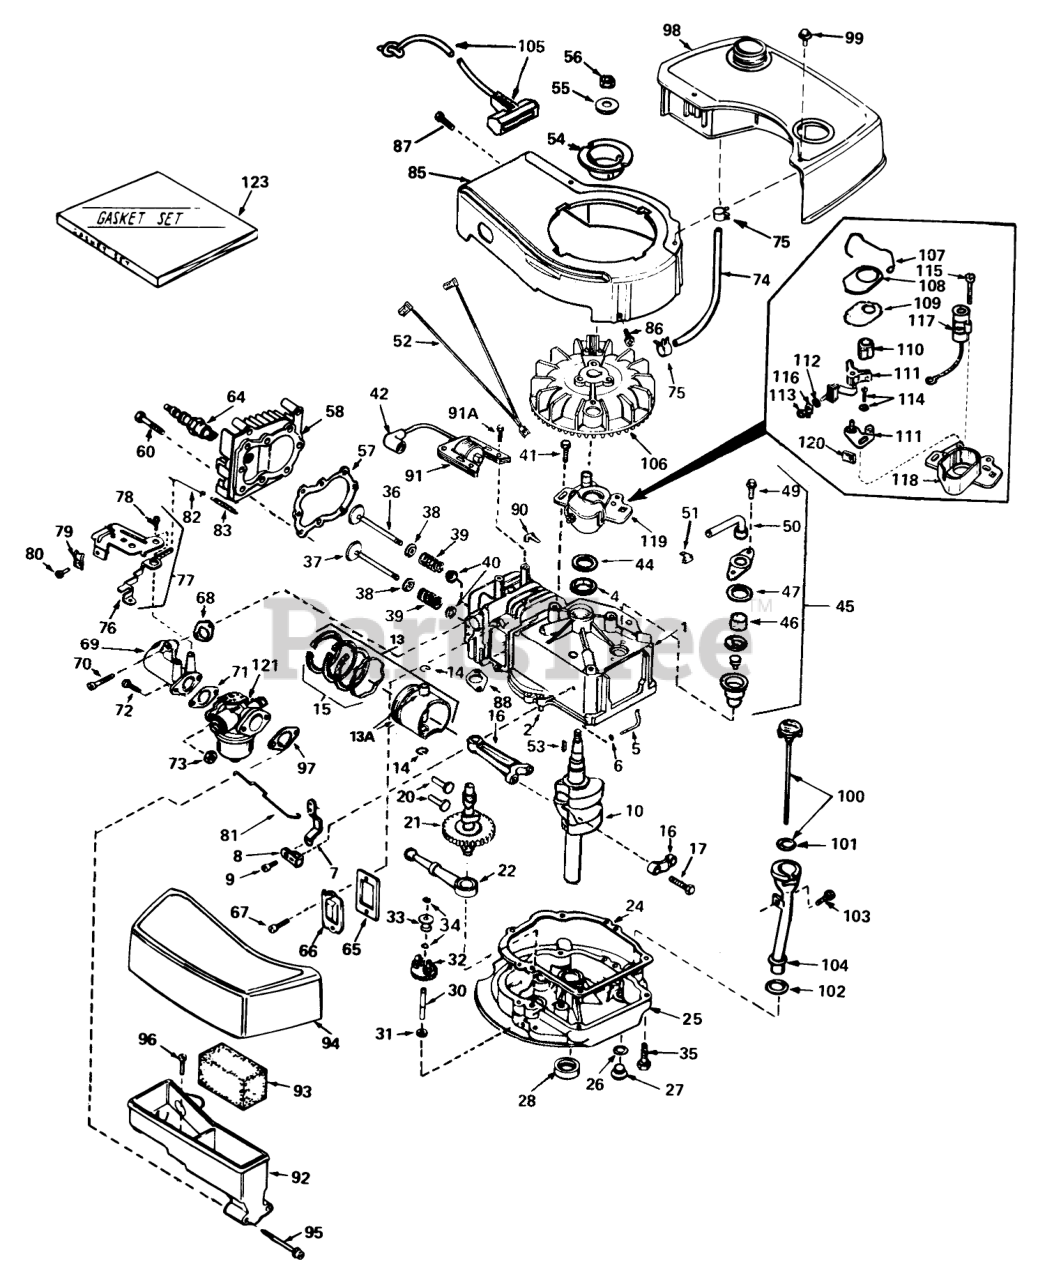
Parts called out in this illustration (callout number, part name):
1	Cylinder Assy. (Incl. #2 & 4)
2	Pin-Dowel
4	Seal-Oil
5	Rod Governor (Incl. #6)
6	Washer-Flat
7	Governor Lever
8	Clamp-Lever, Governor
9	Screw
10	Crankshaft
13	Piston, Pin & Ring Assy. (Incl. #13A, 14 & 15) (Std.)
13	Piston, Pin & Ring Assy. (Incl. #13A, 14 & 15) (.010 Oversize
13	Piston, Pin & Ring Assy. (Incl. #13A, 14 & 15) (.020 Oversize)
13A	Piston & Pin Assembly (Incl. #14) (Std.)
13A	Piston & Pin Assy. (Incl. #14) (.010 Oversize)
13A	Piston & Pin Assy. (Incl. #14) (.020 Oversize)
14	Ring-Retaining, Piston Pin
15	Ring Set Piston (Std.)
15	Ring Set Piston (.010 Oversize)
15	Ring Set Piston (.020 Oversize)
16	Rod Assy., Con. (Incl. #17)
17	Bolt-Rod, Connecting
20	Lifter-Valve
21	Camshaft(Mech.Comp. Release)
22	Oil Pump ASM
24	Gasket, Mounting
25	Flange Assy., Mounting (Incl. #26 thru 30)
26	Gasket-Oil Drain
27	Plug Oil Drain
28	Seal Oil
30	Shaft-Governor
31	Washer-Flat
32	Gear, Assy., Gov. (Incl. #31)
33	Spool-Governor
34	Ring-Retaining
35	Screw (1/4-20 x 1-1/4)
36	Valve lntake (Std.) (Incl. #38, 39 & 40)
36	Valve, Intake (1/32" Oversize) (Incl. #38, 39 & 40)
37	Valve, Exhaust (Std.) (Incl. #38, 39 & 40)
37	Valve, Exhaust (1 /32" Oversize) (Incl. #38, 39 & 40)
38	Cap-Upper Valve Spring
39	Spring-Valve
40	Cap-Valve, Spring
42	Cover-Spark Plug
44	Gasket Stator
45	Breather Assy. (Incl. #46-51)
46	Element-Breather
47	Gasket-Breather
49	Screw (10-24 x 9/16)
50	Tube, Breaker
51	Clip, Breather
52	Wire Ground
53	682488 LB GRASS HI-
54	Hub-Starter
55	Washer-Belleville
56	Nut-Flywheel
57	63573 GIL 42 SNWTHW
58	Head-Cylinder
60	Screw (5/16-18x1-1/2)
64	Plug, Spark (J17LM or equiv.)
64	Plug, Spark (Champion RCJ-8)
65	Gasket-Breather
66	Cover-Valve
68	Gasket, Intake
69	Pipe, Intake
70	Screw (1/4-20 x 1)
71	Gasket-Carburetor
72	Screw (1/4-28 x 7/8)
73	Nut and Lock Washer (1/4-28)
74	Line-Fuel
75	Clamp-Line, Fuel
76	Lever Control
77	Control Assembly, Speed (Incl. #76 & 78)
78	Screw, Hex Washer Hd Shoulder Self-Tap
79	Conduit
80	Screw (10-32 x 3/8)
81	Link-Throttle
82	Link Governor Spring
83	Spring Governor
85	Housing Blower
86	Screw
87	Screw (10-24 x 9/16)
88	Gasket Exhaust
90	Clip-Wire
91	Lamination & Coil Assembly (Incl. #42)
91A	Screw
92	Body Air Cleaner
93	Filer, Air
94	Cove, Air Cleaner
95	Screw Fil Hd.
96	Screw, Hex Hd.
97	Gasket-Air Cleaner
98	Tank, Fuel
99	Screw (10-32 x 35/64)
100	Dipstick, Oil (Incl. #101) (Twist Lock)
103	Screw (10-32 x 1/2)
104	Tube-Oil Fill
105	Rope Assy., Starter
106	FIywheel
107	Spring Breaker Box
108	Cover-Dust
109	Gasket-Dust Cover
110	Cam-Breaker
111	Breaker Assy.
114	Breaker Screw
115	Condenser Screw
116	Terminal, Ground
117	Condenser
118	Stator Plate
119	Stator Plate Assy. (Incl. #107, 111 thru 118 & 120)
120	Felt,Cam Wiper
121	Carburetor (Incl. #71)
123	53024/VAR.16HP O/P
